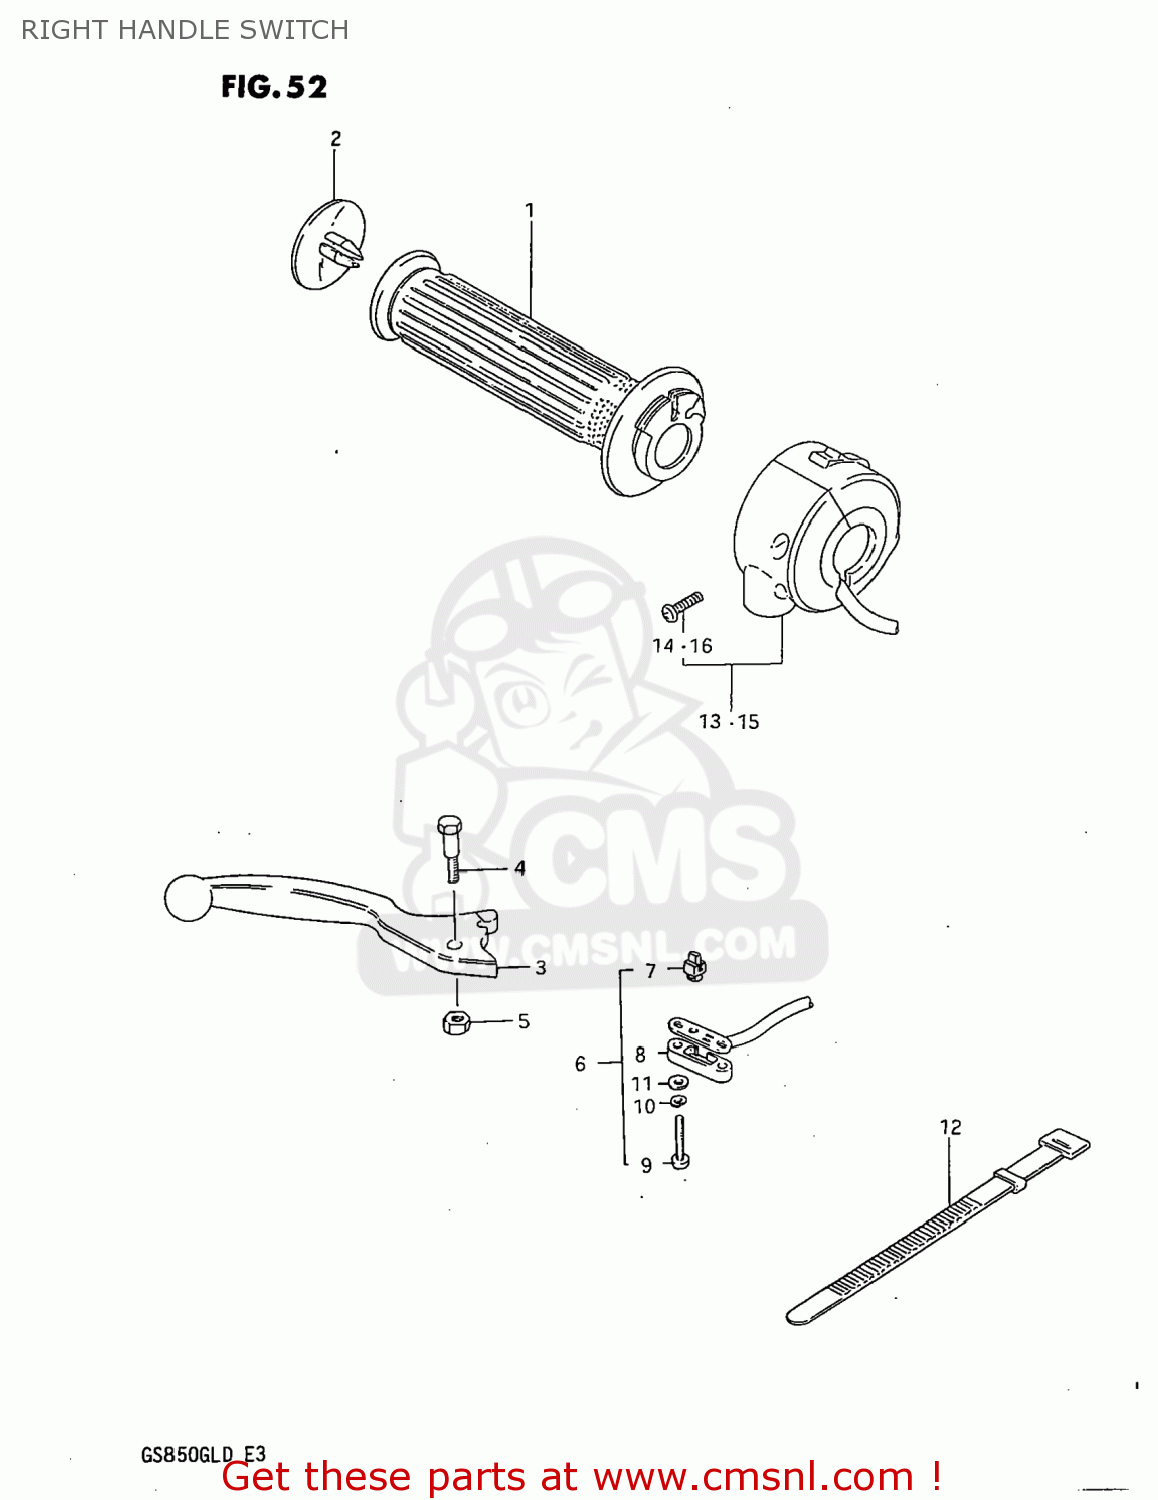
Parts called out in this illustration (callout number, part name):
1	GRIP,THROTTLE
2	CAP,GRIP END
3	LEVER,BRAKE
4	BOLT
5	NUT 6MM
6	SWITCH ASSEMBLY
7	CONTACT,SWITCH
8	COVER,FR BK TERMINAL BASE
9	SCREW
10	LOCK WASHER
11	WASHER
12	CLAMP(L:120)
13	SWITCH ASSEMBLY,HANDLE,RIGHT
14	SCREW
15	SWITCH ASSEMBLY,HANDLE,RIGHT
16	SCREW
